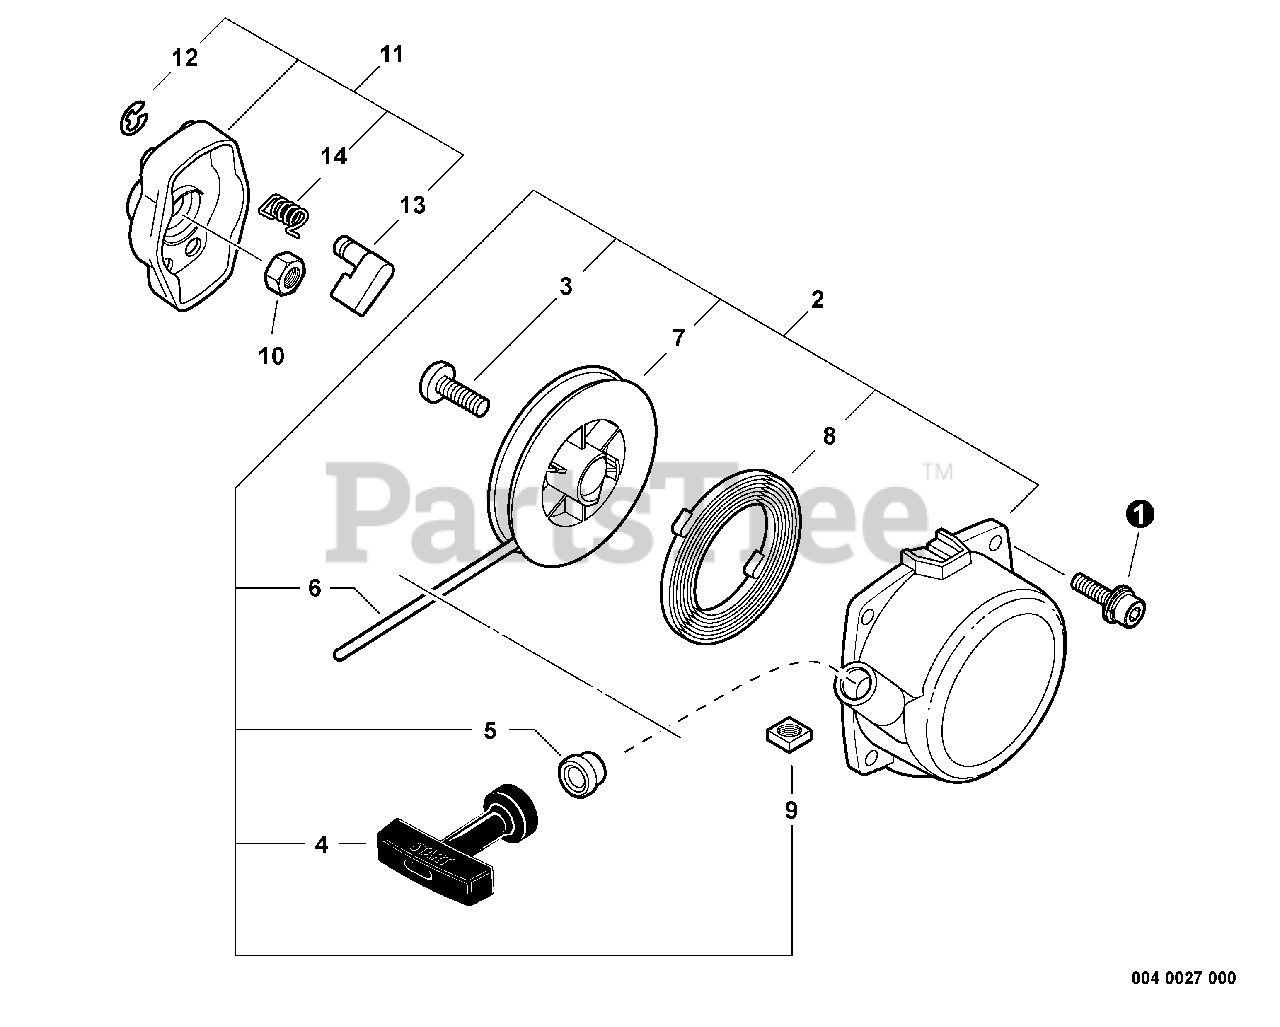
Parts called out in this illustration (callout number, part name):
1	SCREW - 4X12
2	STARTER ASSY
4	GRIP, STARTER
5	GUIDE, ROPE
6	ROPE, STARTER - 3.5X850
7	REEL, ROPE
8	SPRING, REWIND
9	NUT - 5 -- SQUARE
11	STARTER PAWL ASSY
12	RING, RETAINING - 4
13	PAWL, STARTER
14	SPRING, RETURN
